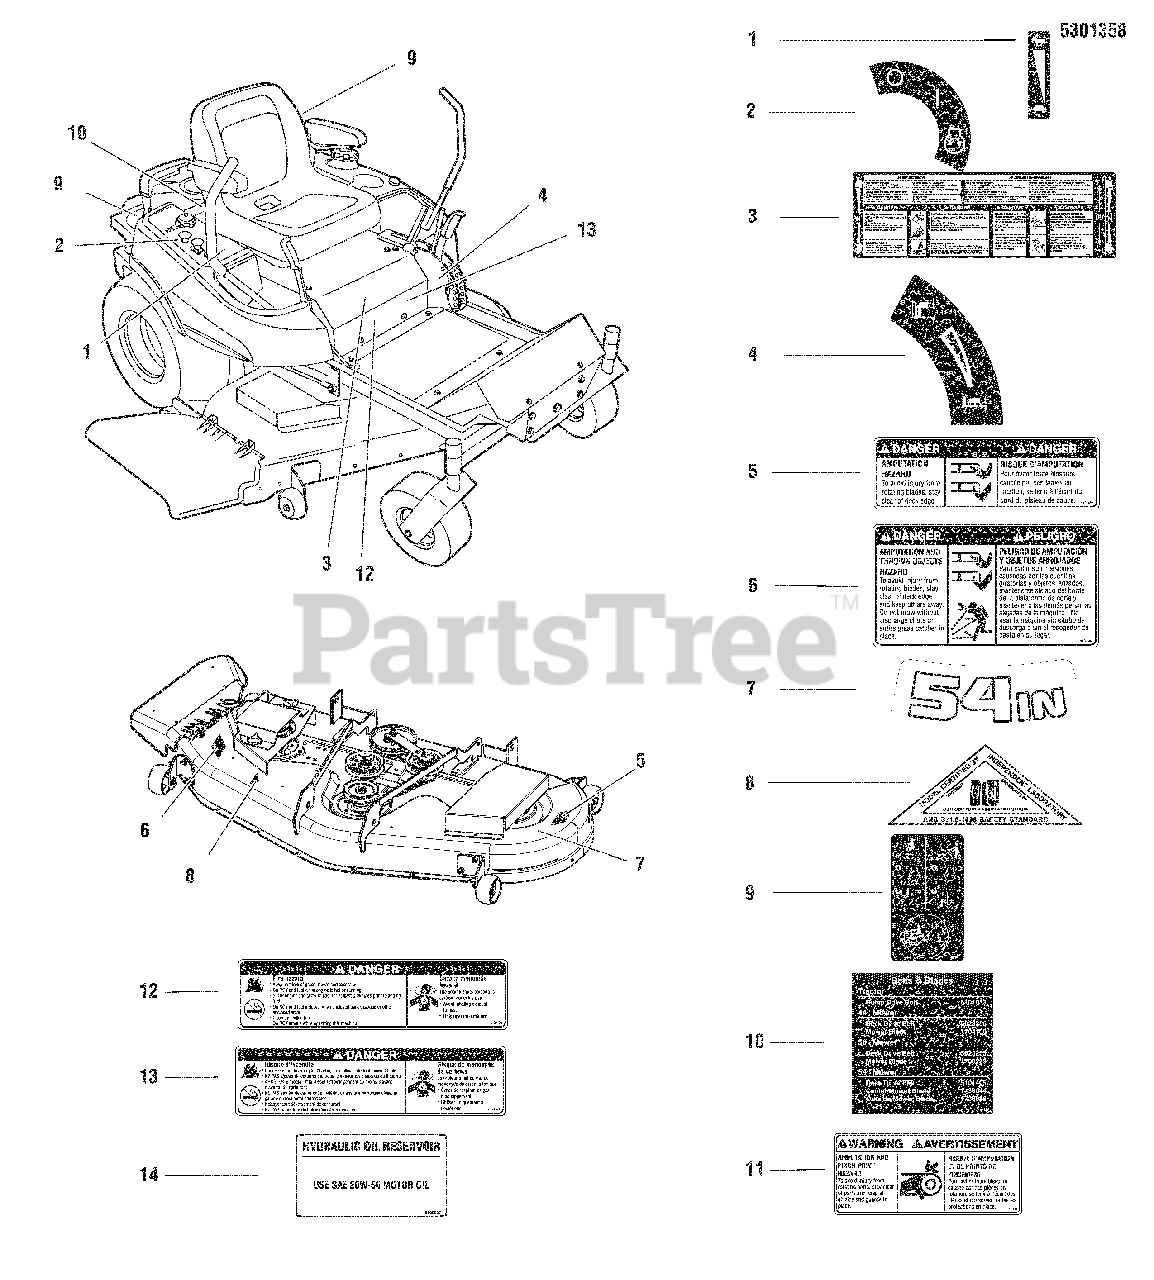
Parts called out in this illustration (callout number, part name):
1	DECAL, THROTTLE CONTROL
2	DECAL, IGNITION SWITCH
3	DECAL, MAIN, SNAPPER 355ZB2654 (FC)
4	DECAL, HEIGHT OF CUT
5	DECAL, DANGER, MOWER (FC)
6	DECAL, DANGER, MOWER DISCHARGE, 5.5 X 3.0 (FC)
7	DECAL, 54"
8	DECAL, OPEI WALK/RIDE
9	DECAL, TRANSAXLE RELEASE
10	DECAL, BELT & BLADE SNAPPER
11	DECAL, WARNING, HAND IN PULLEY (FC)
12	DECAL, DANGER, FIRE
13	DECAL, DANGER, FIRE (FC)
14	DECAL, HYDRAULIC OIL, SAE 20W50
